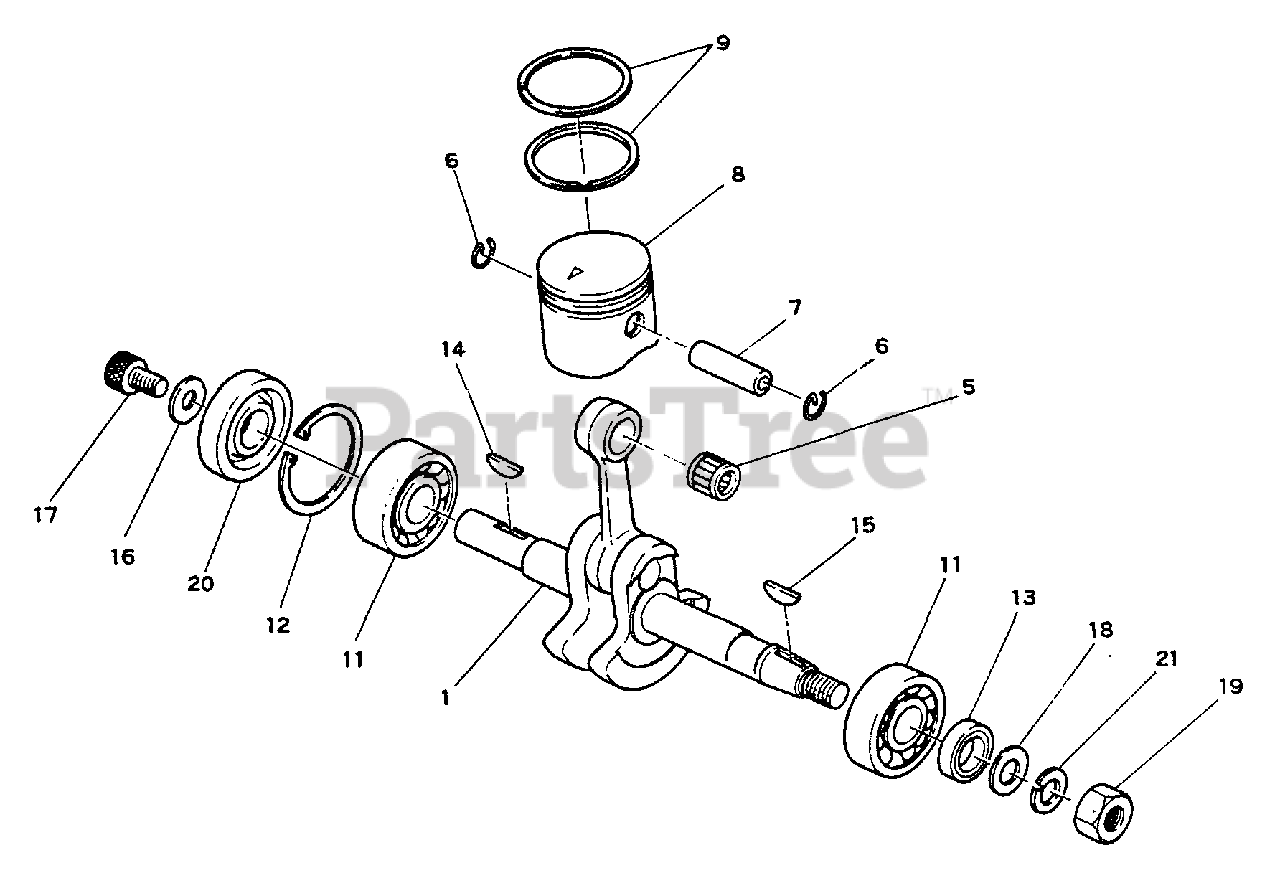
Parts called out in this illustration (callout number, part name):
1	CRANKSHAFT ASSY
5	BEARING, NEEDLE 8
6	RING, SNAP
7	PIN, PISTON
8	PISTON
9	RING, PISTON
11	BEARING, BALL - 6201 C3
12	RING, SNAP Ø32
13	SEAL, OIL
16	WASHER 6
17	BOLT M6×10
19	NUT 8×1.25
20	SEAL, OIL 12
21	WASHER, SPRING 8
